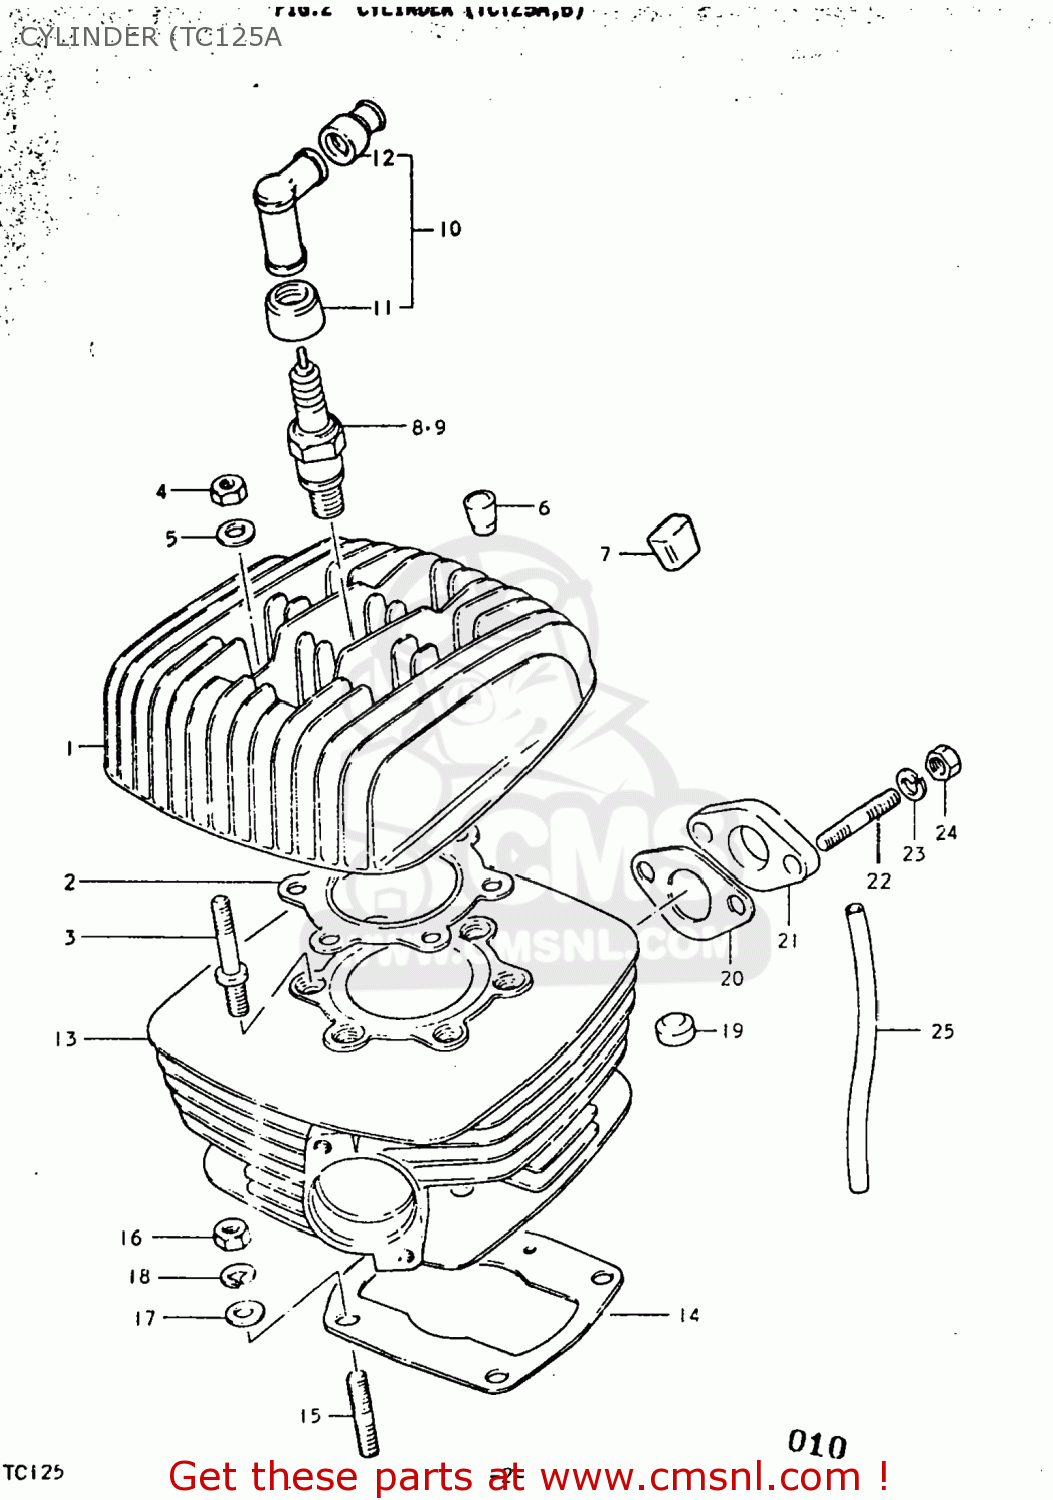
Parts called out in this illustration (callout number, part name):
1	HEAD,CYLINDER
2	GASKET,CYLINDER HEAD (MCA)
3	BOLT,STUD
4	NUT (8MM)
5	WASHER
6	PAD,CYLINDER HEAD
7	PAD,CYLINDER
8	SPARK PLUG
9	SPARK PLUG
10	CAP,SPARK PLUG
11	SEAL,SPARK PLUG
12	SEAL,SPARK PLU
13	CYLINDER
14	GASKET,CYLINDER (MCA)
15	STUD 8X25
16	NUT
17	WASHER
18	LOCK WASHER
19	PAD,CYLINDER
20	GASKET,CARB (MCA)
21	INSULATOR,CARBURETOR
22	STUD BOLT
23	LOCK WASHER
24	NUT
25	HOSE
